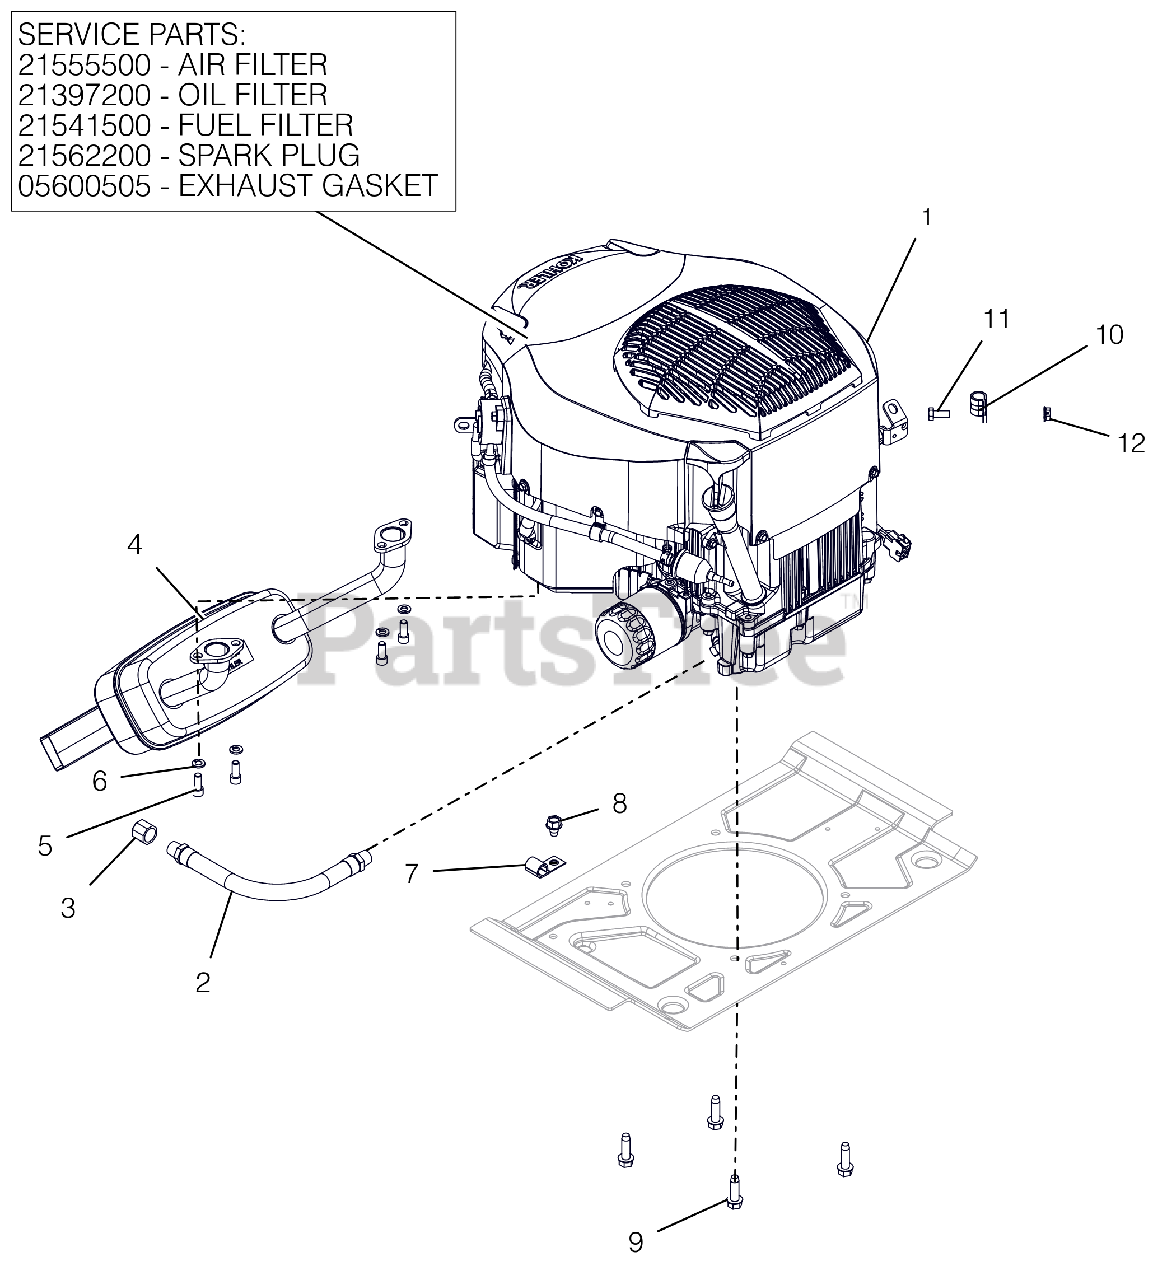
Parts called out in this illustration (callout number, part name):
1	ENGINE, KOHLER TWIN 23 HP
1	AIR CLEANER, KOHLER
1	FILTER, OIL - KOH CV20
1	FILTER, FUEL
1	PLUG, SPARK (RFI)
1	GASKET, MUFFLER COURAGE TWIN
2	HOSE,HYD .38-11-0K M6NO-M6N0
3	PIPE CAP 3/8 NPT FEMALE
4	MUFFLER, KOHLER
5	SCR-CAP .31-18X.75 S/HD
6	@WSHR-LK .31X.078 REG YWZC
7	J-CLAMP
8	@SCR-TAP .38-16X.50 HWH TR YWZ
9	@SCR-TAP .38-16X1.25 HWH TR YZ
10	CLAMP, CUSHIONED STEEL
11	@BLT-HEX .31-18X.75 GR5 YWZC
12	@NUT-LK-CTR-FLG .31-18 YZ GR F
